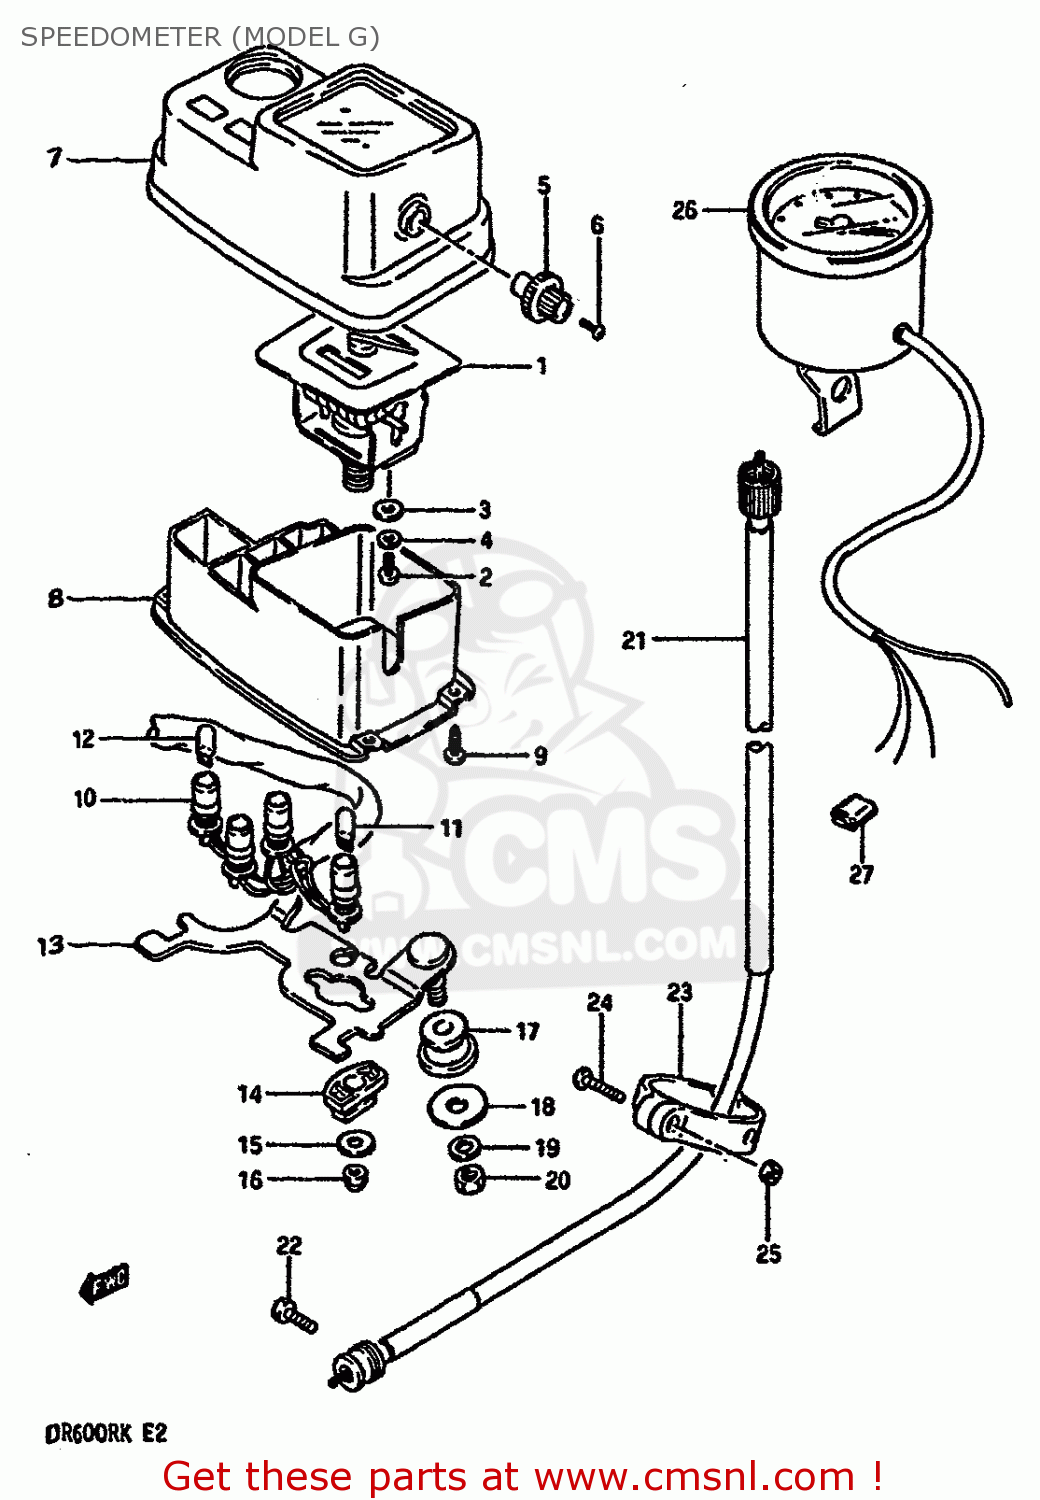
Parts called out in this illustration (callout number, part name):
1	SPEEDOMETER (KILO)
2	SCREW
3	WASHER
4	LOCK WASHER
5	KNOB,TRIP
6	ROTOR,SPEED
7	HOOD,METER
8	CASE,METER
9	SCREW
10	SOCKET,METER
11	BULB(12V3.4W,T10)
12	BULB(12V1.7W,T10,WB121)
13	BRACKET,METER
14	CUSHION
15	WASHER
16	NUT
17	CUSHION,METER BRACKET
18	WASHER (8.5X20X1.6)
19	WASHER,LOCK,8.
20	NUT
21	CABLE ASSEMBLY,SPEEDOMETER
22	BOLT
23	CLAMP,SPEEDOMETER CABLE
24	SCREW 5X20
25	NUT
26	METER,TACHOMETER
27	CONNECTOR,LEAD WIRE
